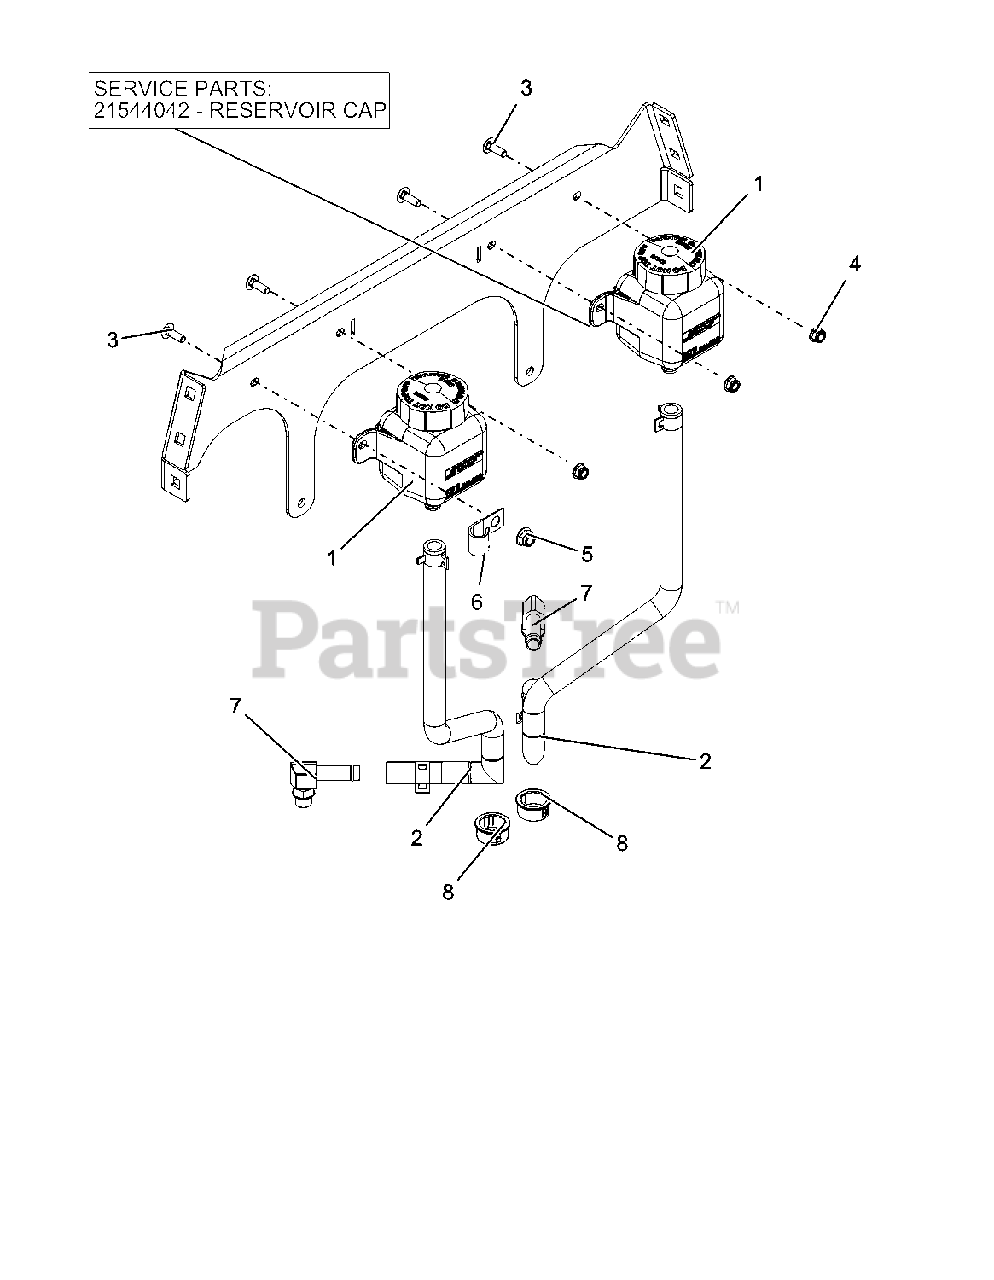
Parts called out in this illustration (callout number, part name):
1	TANK, EXPANSION
1	CAP, HYDRO RESERVOIR REPLAC.
2	HYDRO, SYSTEM PRO-STANCE
3	@BLT-RDHDSQNK .25-20X.75 G5YZ
4	@NUT-LK-NYL-FLG .25-20 YWZC
5	@NUT-LK-NYL-FLG .31-18 YWZC
7	FITTING, HYD (90 DEG)
8	BSHG, PANEL SNAP .937X1.11X.56
